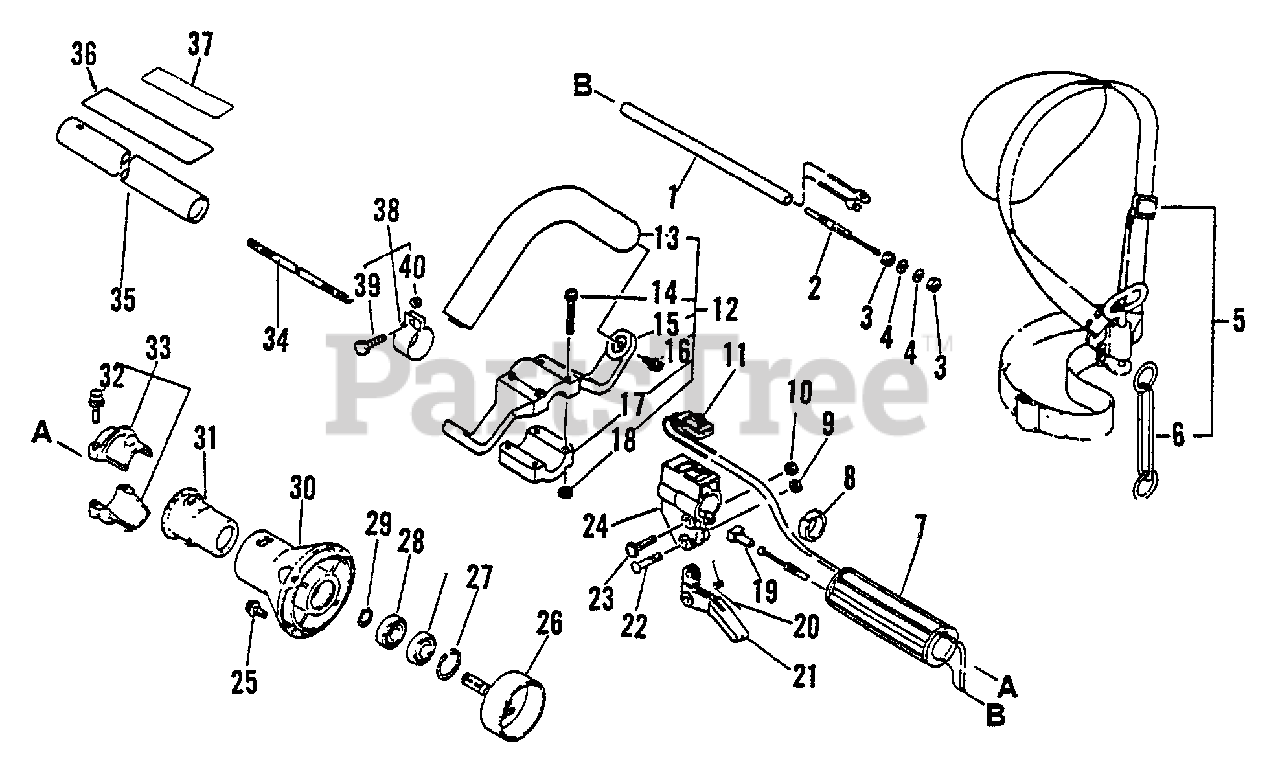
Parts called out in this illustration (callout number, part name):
1	TUBE - VINYL
2	CABLE, THROTTLE
3	WASHER 6.5×11.5×0.8
5	SHOULDER STRAP ASSY
6	HOOK
7	GRIP
8	SPACER
9	NUT, LOCK M5
10	NUT M5
11	SWITCH, ON-OFF
12	HANDLE ASSY
13	HANDLE
14	SCREW 5×35
15	BRACKET, HANDLE
16	SCREW 5×14
17	BRACKET, HANDLE
18	NUT M5
19	GUIDE, CABLE
20	SPRING, THROTTLE
21	TRIGGER, THROTTLE
23	SCREW 5×30
24	BRACKET, THROTTLE CONTROL
25	SCREW 5×16
26	DRUM, CLUTCH
27	RING, SNAP 28
28	BEARING, BALL 6001
29	RING, RETAINING - 12
30	CASE, CLUTCH
32	BOLT - 5×25
33	HOLDER KIT
34	DRIVESHAFT
35	MAIN PIPE ASSY 25×1500
36	LABEL - CAUTION
37	LABEL - CAUTION
38	HOOK
39	BOLT 5×18
40	SPACER, GUARD
